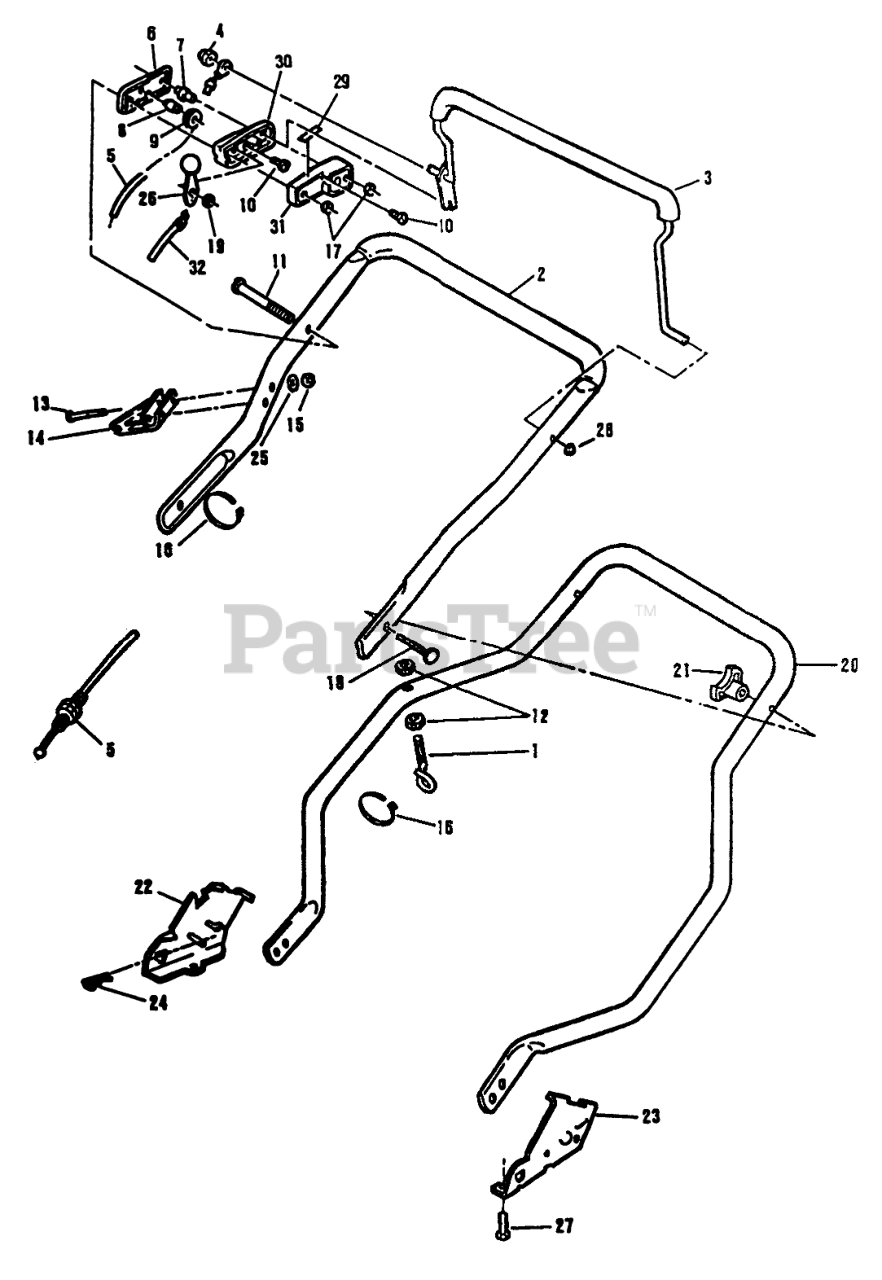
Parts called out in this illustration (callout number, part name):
1	EYE BOLT WAS MFG
2	HANDLE SECTION B
3	CONTROL LEVER ARG
4	NUT ACORN
5	CONTROL CABLE WES
6	OUTER CONTROL CASE
7	COLUMN
8	PIN SKF
9	PULLEY PL
10	SCREW
11	SCREW
12	LOCKNUT E
13	SCREW
14	GUIDE - ROPE
15	LOCKNUT E
16	TIE-CABLE
17	NUT C/LOCK E
18	Screw
19	WASHER-SPRING
20	HANDLE SECTION B
21	Knob
22	HANDLE BRKT&PIN WA
23	HANDLE BRKT&PIN WA
24	HAIR PIN
25	WASHER
26	LEVER&KNOB AY WES
27	SCREW
28	NUT-PUSH
29	DECAL-THROT CONTRL
30	CENTER CONTROL CASE
31	INNER CONTROL CASE
32	CABLE THROT WES
